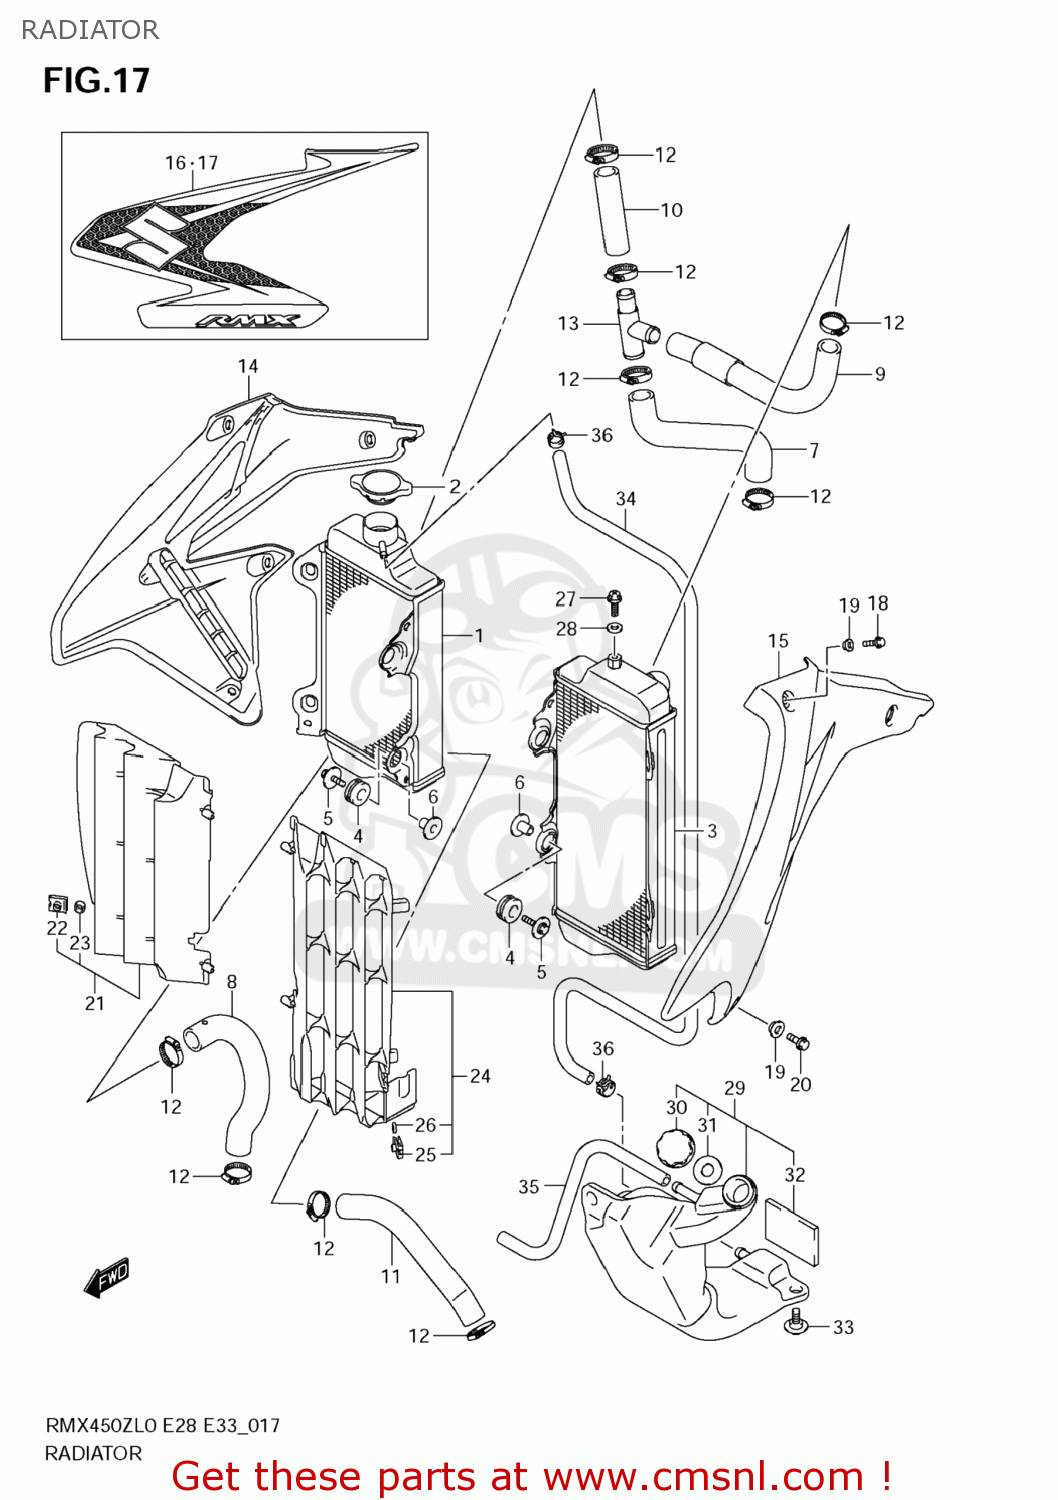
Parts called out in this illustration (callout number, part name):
1	RADIATOR,WATER
2	CAP COMP,RADIATOR
3	RADIATOR,WATER,L
4	CUSHION,RADIATOR LWR
5	BOLT(6X25)
6	SPACER(6.5X10.5X14.1)
7	HOSE,RADIATOR INLET
8	HOSE,RADIATOR OUTLET
9	HOSE,RADIATOR JOINT UPR NO.1
10	HOSE,RADIATOR JOINT UPR NO.2
11	HOSE,RADIATOR JOINT LWR
12	CLAMP
13	JOINT,RADIATOR HOSE
14	COVER,RADIATOR
15	COVER,RADIATOR
16	TAPE,FUEL TANK COVER,R
17	TAPE,FUEL TANK COVER,L
18	BOLT(6X12)
19	WASHER,FUEL TANK COVER
20	BOLT(6X16)
21	LOUVER,RADIATOR,R
22	NUT
23	SPACER(6.2X10X2.2)
24	LOUVER,RADIATOR,L
25	NUT
26	SPACER(6.2X10X2.2)
27	UNION BOLT,AIR VENT
28	GASKET(6.4X11.5X0.8) (NAS)
29	TANK ASSY,RESERVOIR
30	CAP,WATER RESERVOIR TANK
31	GASKET,RSVR TANK CAP (NAS)
32	CUSHION
33	BOLT,RESERVOIR TANK
34	HOSE,RESERVOIR TANK INLET
35	HOSE(5X9X600)
36	CLIP
